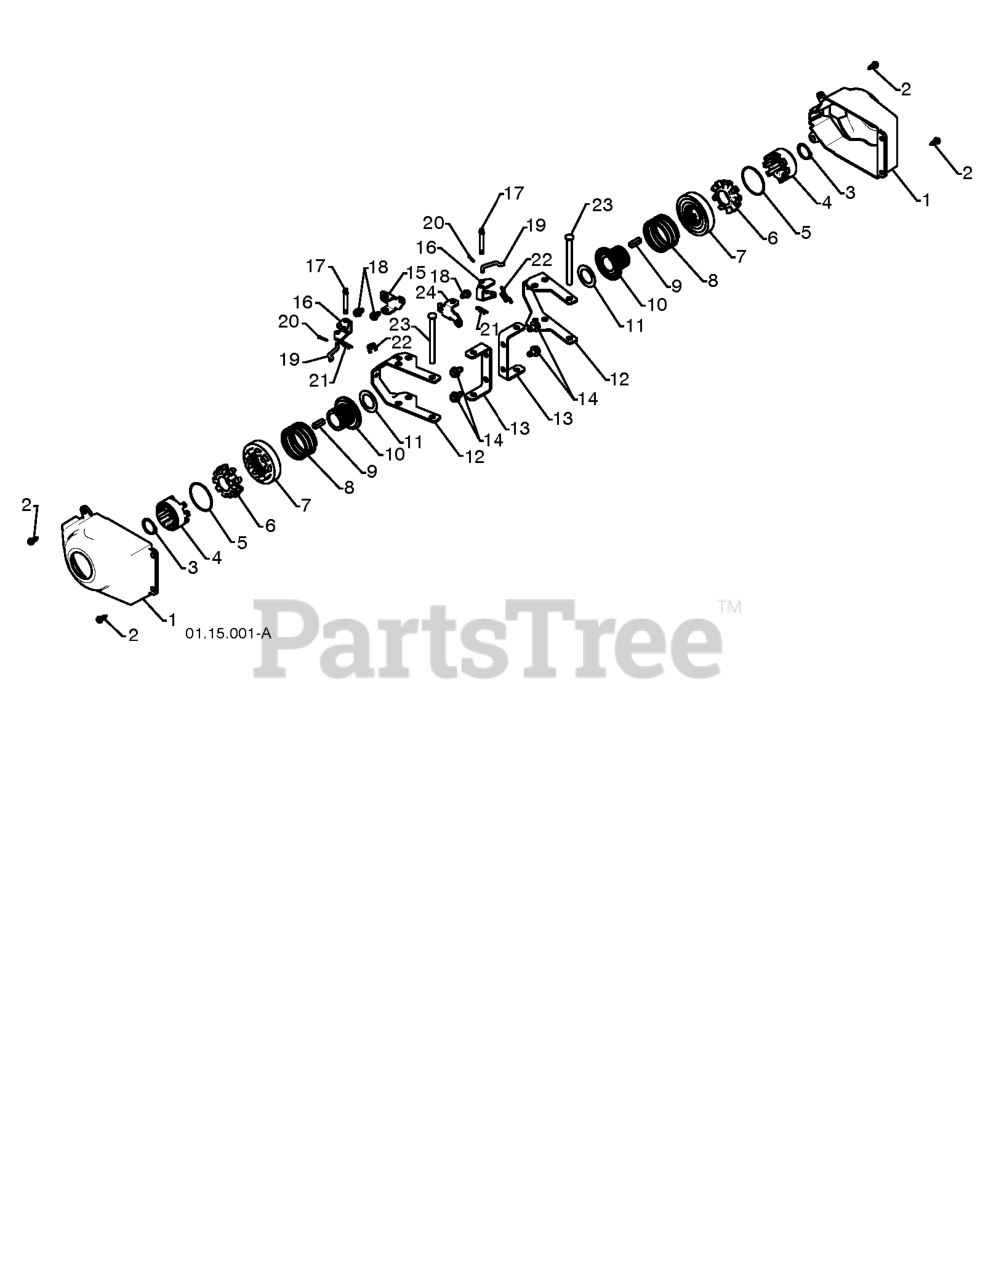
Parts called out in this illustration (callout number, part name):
1	COVER, POWER STEERING
2	SCREW, HEX HEAD, TAPPING
4	RP.DRIVER WHEEL
5	RING, WIRE RETAINER
6	LOBE WHEEL
7	RP.SLIDE.CLUTCH
8	SPRING, CLUTCH SLIDE
9	KEY, SQUARE 1/4 X .875
10	RP.LOBE.AXLE
11	WASHER TRUST 1"
12	YOKE.PNT.WELDMENT.STEE
13	BRACKET
14	Screw 5/16-18 x 1/2 Hex, Self Tapping 5/16-18 x 1/2
15	BRKT.STEER.PIVOT.RH
16	BELLCRANK.STEER
17	PIN, STEERING BELLCRANK
18	SCREW 1/4X20
19	LINK.STEER.YOKE
20	RETAINER CLIP
21	RETAINER CLIP PM
22	SPRING LATCH
23	PIN, STEERING LEVER
24	BRACKET.STEER.PIVOT.LH.YZ
